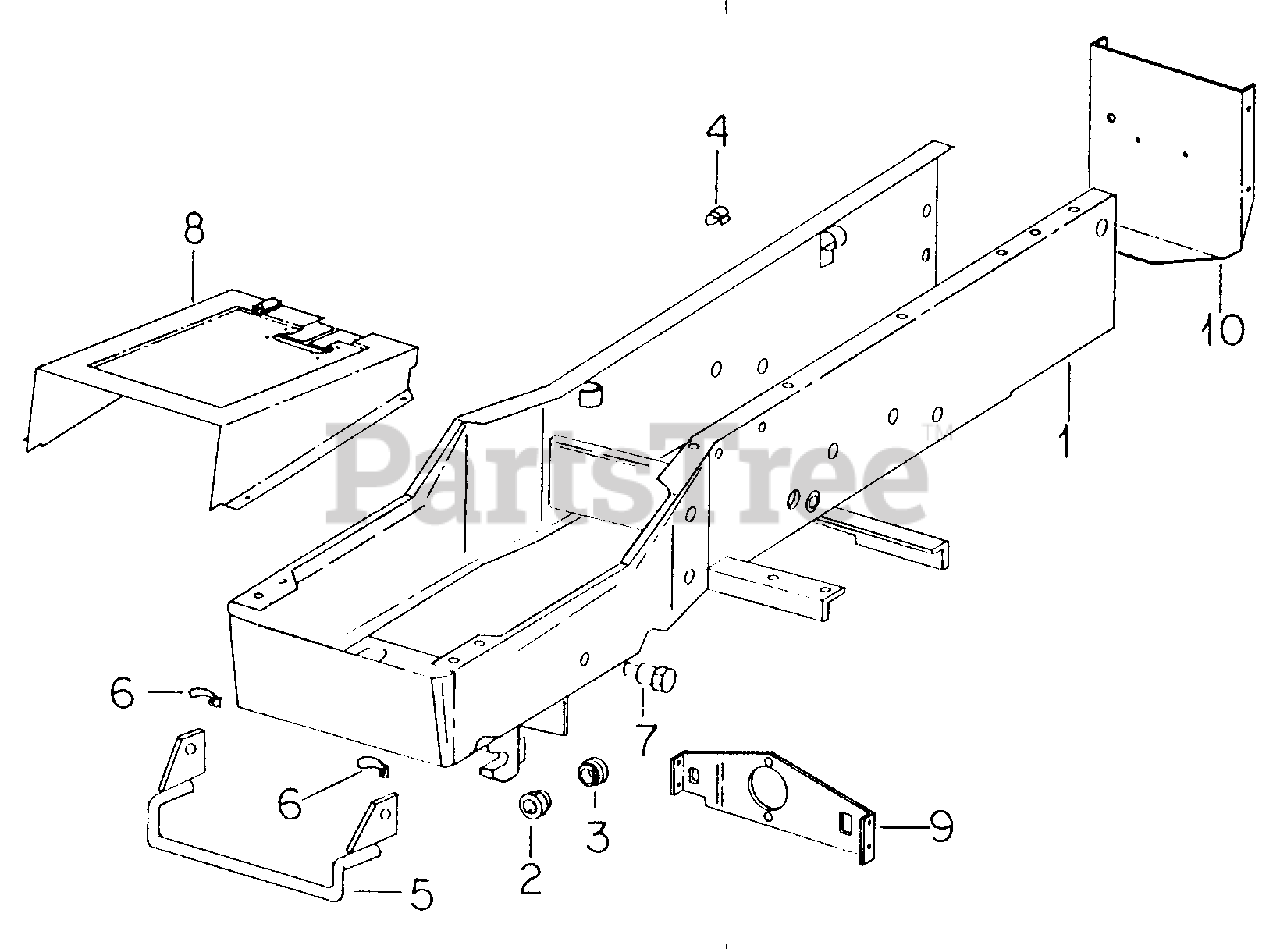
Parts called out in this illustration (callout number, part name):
1	Frame Assy, Main
2	Bushing, Front Axle Pivot Pin
3	Bushing, Front Axle Pivot Pin Rear
4	Clip, Cable
5	Hitch Assy, Quick
6	Spring, Latch
7	Bolt, Implement Mtg Shoulder
8	Cover Assy, Frame w/Product Graphic
9	Bracket, Angle Drive
